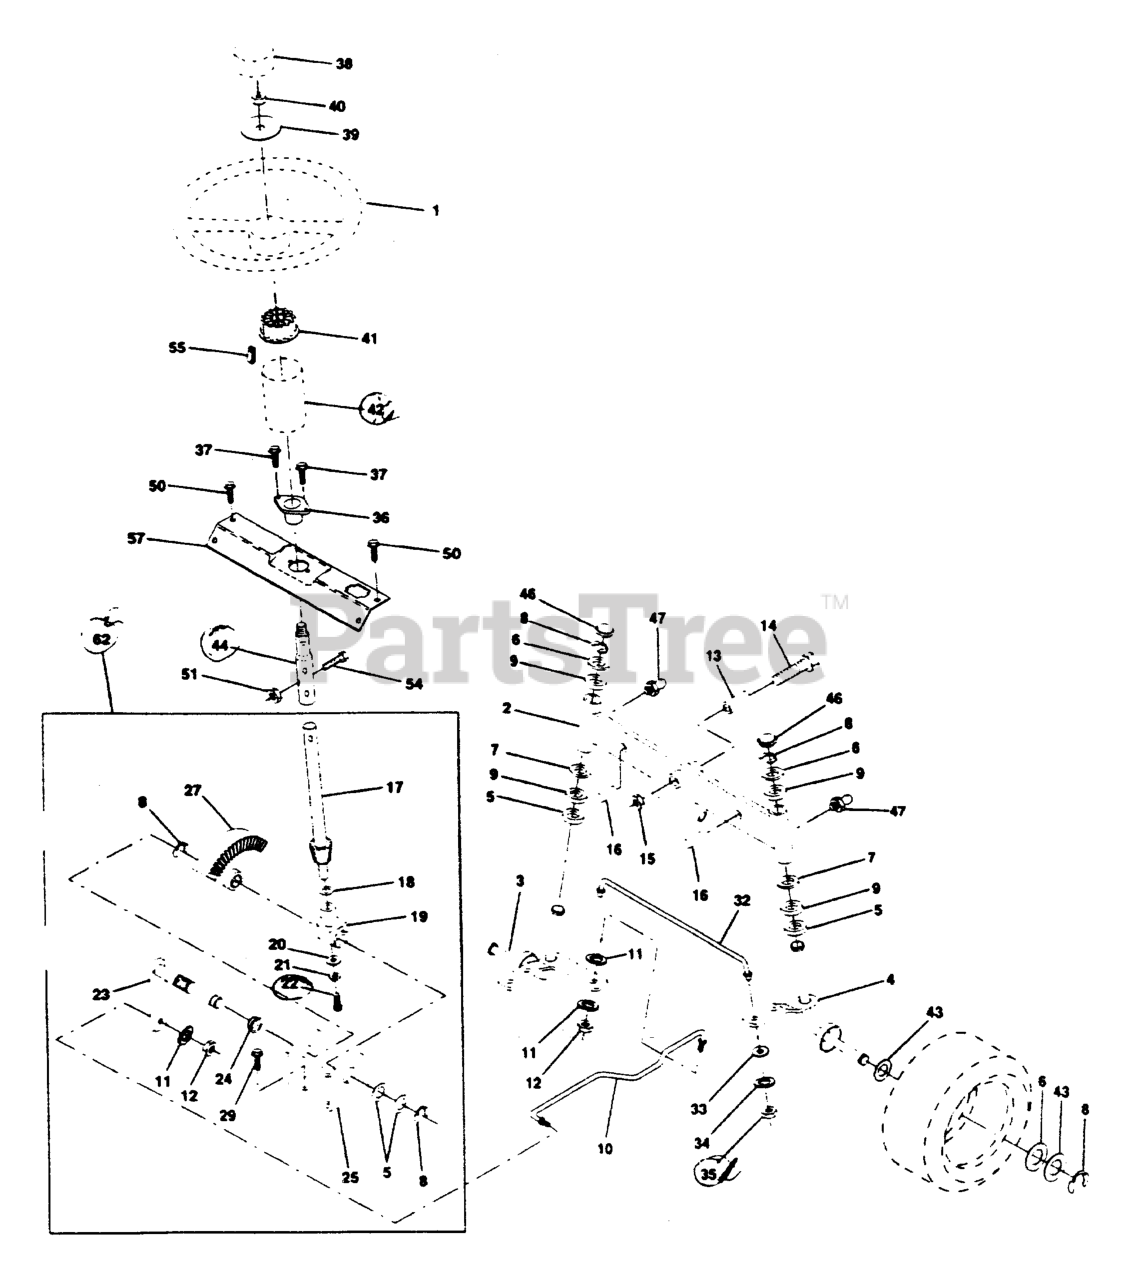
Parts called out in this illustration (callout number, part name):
1	STEERING WHEEL
3	SPINDLE LH
4	SPINDLE RH
5	THRUST WASHER
9	BRNG T
10	LINK.DRAG.SOL.BALL JT.20.064
11	WASHER, LOCK 3/8
12	NUT
13	BEARING
14	Bolt, Hex Head 5/8-11 x 3-1/2
15	NUT-LOC,FLANGE LT
17	SHAFT STEERING
18	THRUST WASHER
19	SHAFT,SUPPORT
20	WASHER
21	LOCKWASHER
22	SCREW
23	SHAFT PITMAN
24	NYLINER T (7283A)
25	BRKT,STEERING
27	GEAR.SECTOR
29	SCREW
32	TIE ROD
33	WASHER M
34	WASHER.LOCK.HVY.HLCL.SPR.5/16
36	BUSHING-STRG LT
37	SCREW LT
38	INSERT,STR WHEEL
39	WASHER T
40	GRIPCO NUT
41	ADAPTER-WHEEL LT
42	BOOT, STEERING SHAFT
44	STEERING SHAFT
46	CAP.SPINDLE.BLACK
47	ZERK M
50	SCREW HEX CRT
51	NUT.71038.31-18.HEX.NYLOCK
54	BOLT.5/16-18X1-1/4 FULL.THREAD
57	SUPPORT STEERING SHAFT
62	KIT, STEERING ASSEMBLY
